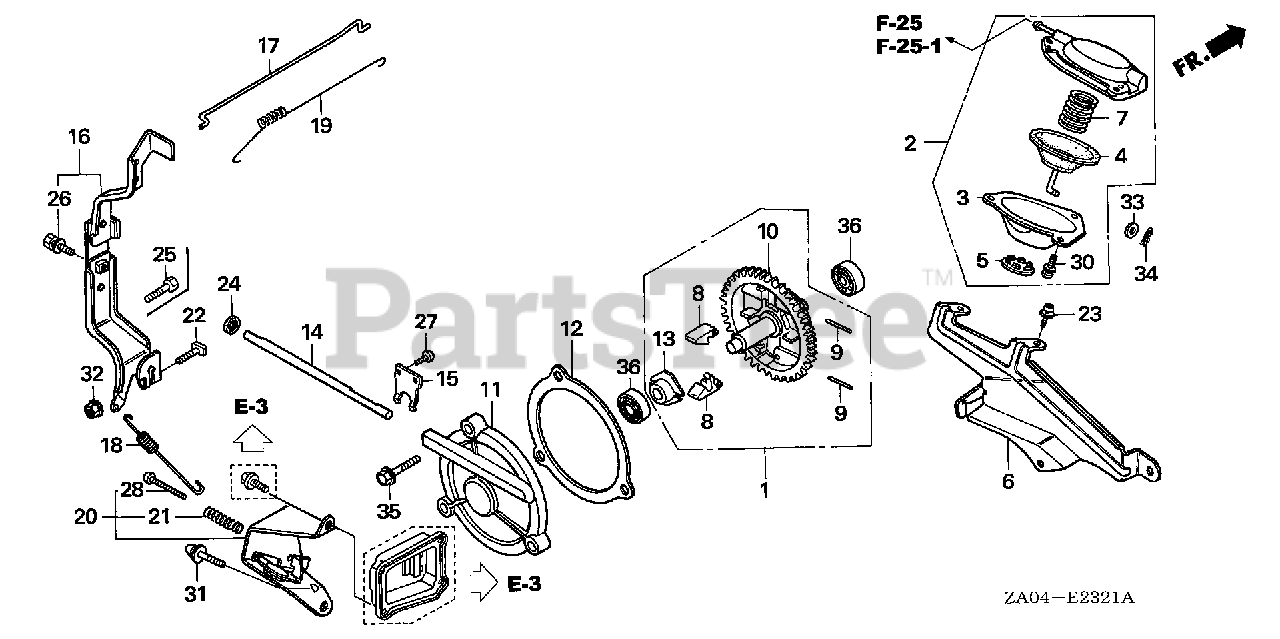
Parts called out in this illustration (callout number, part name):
1	GOVERNOR KIT
2	DIAPHRAGM ASSY.
3	COVER, DIAPHRAGM
4	DIAPHRAGM
5	BUSH, DIAPHRAGM COVER
6	STAY ASSY., DIAPHRAGM
7	SPRING, COIL
8	WEIGHT, GOVERNOR
9	PIN, GOVERNOR WEIGHT
10	SHAFT, GOVERNOR
11	COVER, GOVERNOR
12	GASKET, GOVERNOR COVER
13	SLIDER, GOVERNOR
14	SHAFT, GOVERNOR ARM
15	FORK, GOVERNOR
16	ARM, GOVERNOR
17	ROD, GOVERNOR
18	SPRING, GOVERNOR
19	SPRING, THROTTLE RETURN
20	CONTROL
21	SPRING, CONTROL ADJUSTING Use from Engine SN 2327377.
22	BOLT, GOVERNOR ARM
23	SCREW-WASHER (5X8)
24	OIL SEAL (8X14X5)
26	BOLT-WASHER (6X12)
27	SCREW, PAN (3X8)
28	SCREW, PAN (5X28)
30	SCREW-WASHER (4X8)
31	BOLT, FLANGE (8X12)
32	NUT, FLANGE (6MM)
33	WASHER, PLAIN (4MM)
34	PIN, LOCK (4MM)
35	BOLT, FLANGE (6X25)
36	BEARING, RADIAL BALL (6000)
